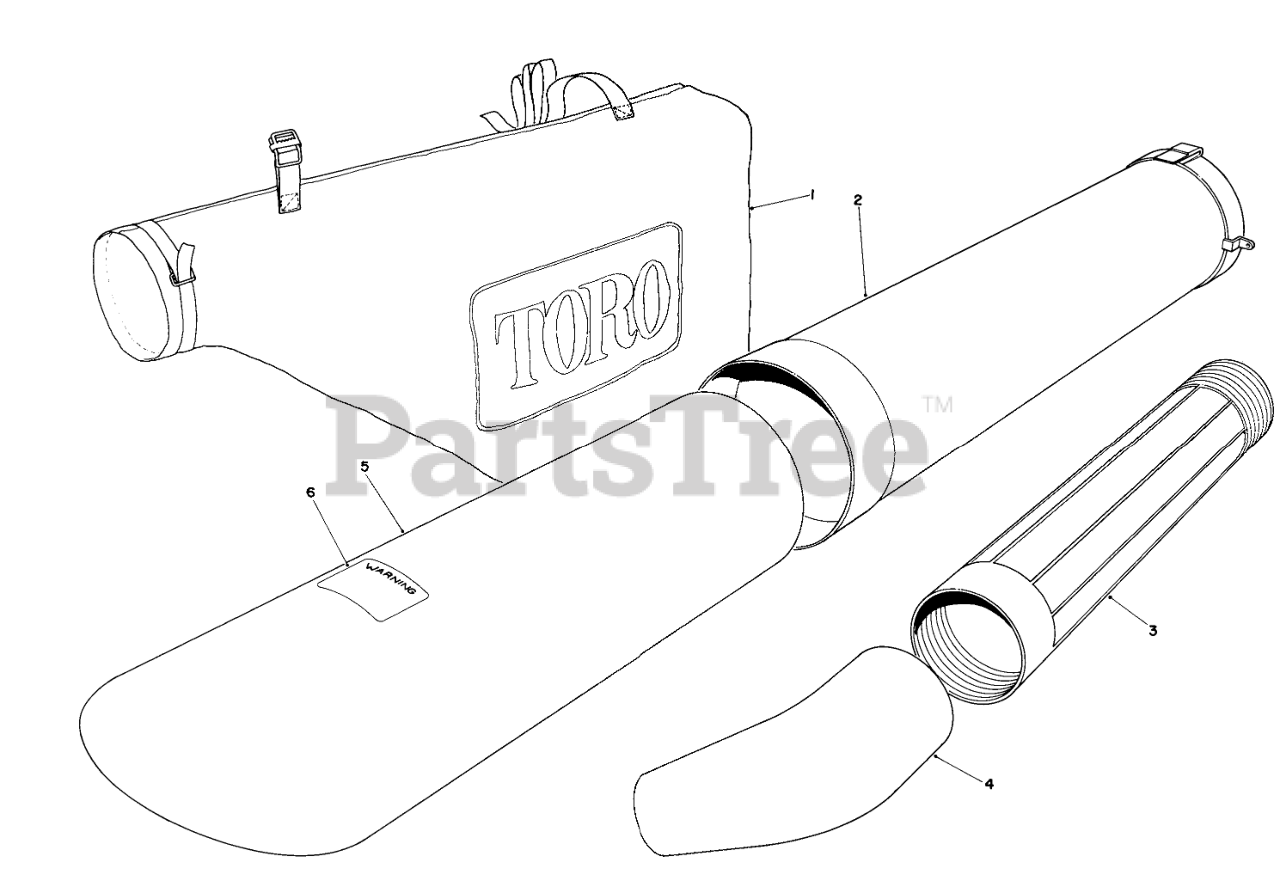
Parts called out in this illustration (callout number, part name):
1	Vacuum Bag
2	Vacuum Tube-Upper
3	Tube
4	Nozzle-Curved
5	Vacuum Tube Assy.-Lower
6	Decal-Warning
